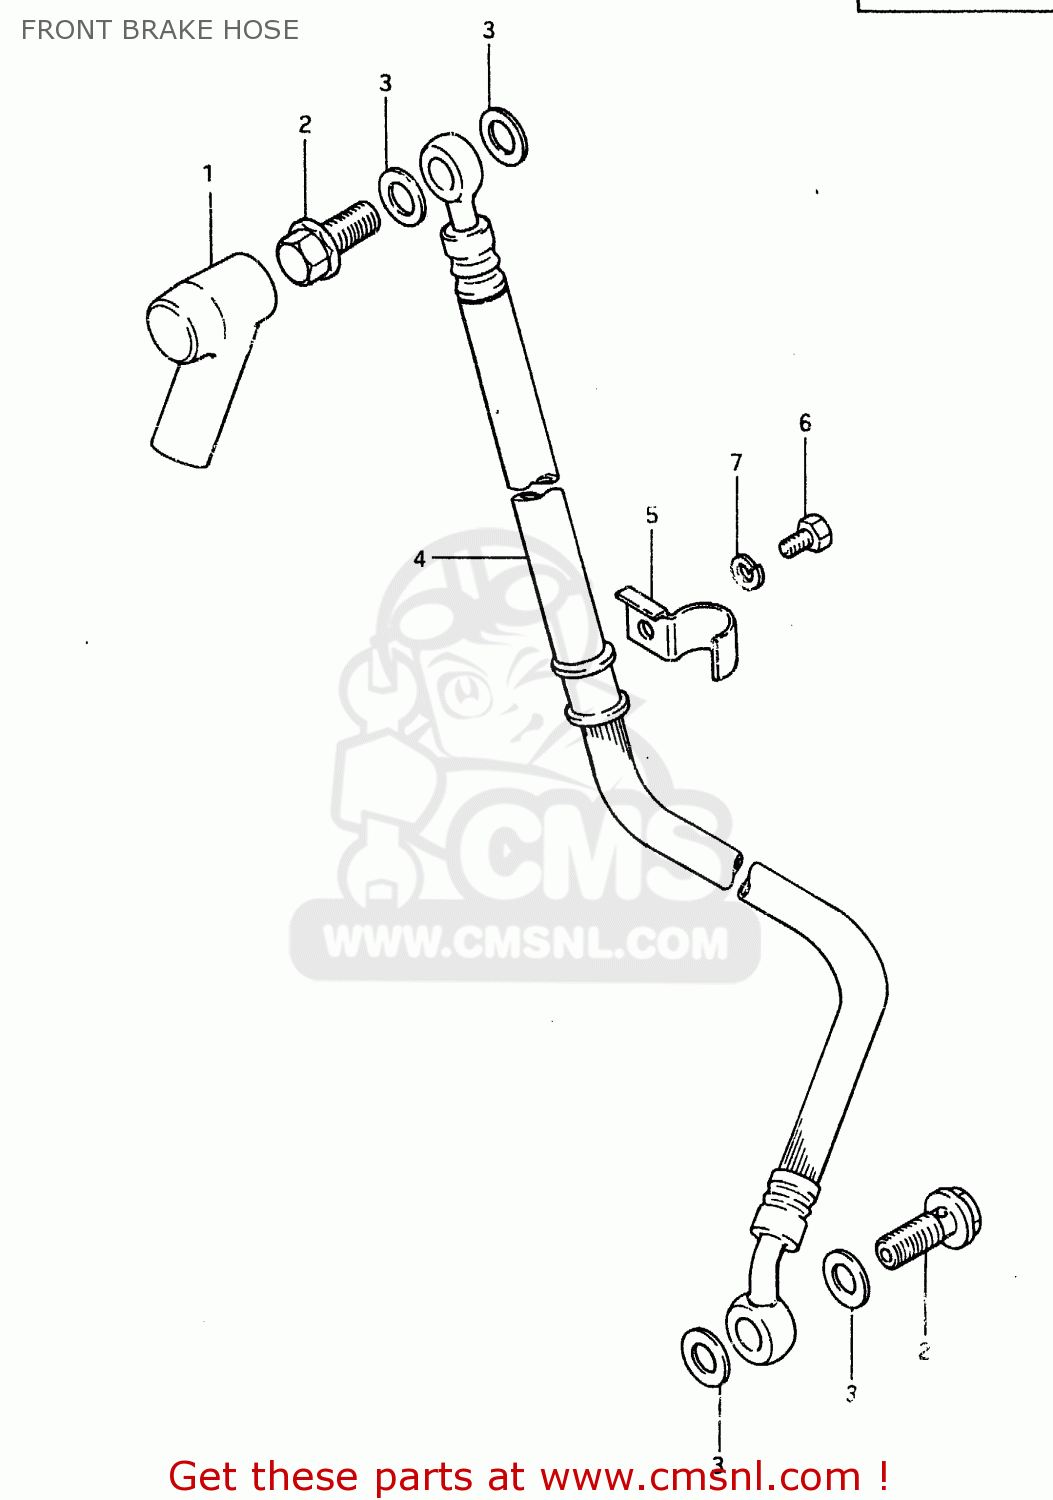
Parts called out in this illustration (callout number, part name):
1	BOOT,MASTER CYLINDER
2	BOLT,UNION
3	WASHER
4	HOSE, BRAKE
5	CLAMP
6	BOLT
7	LOCK WASHER
